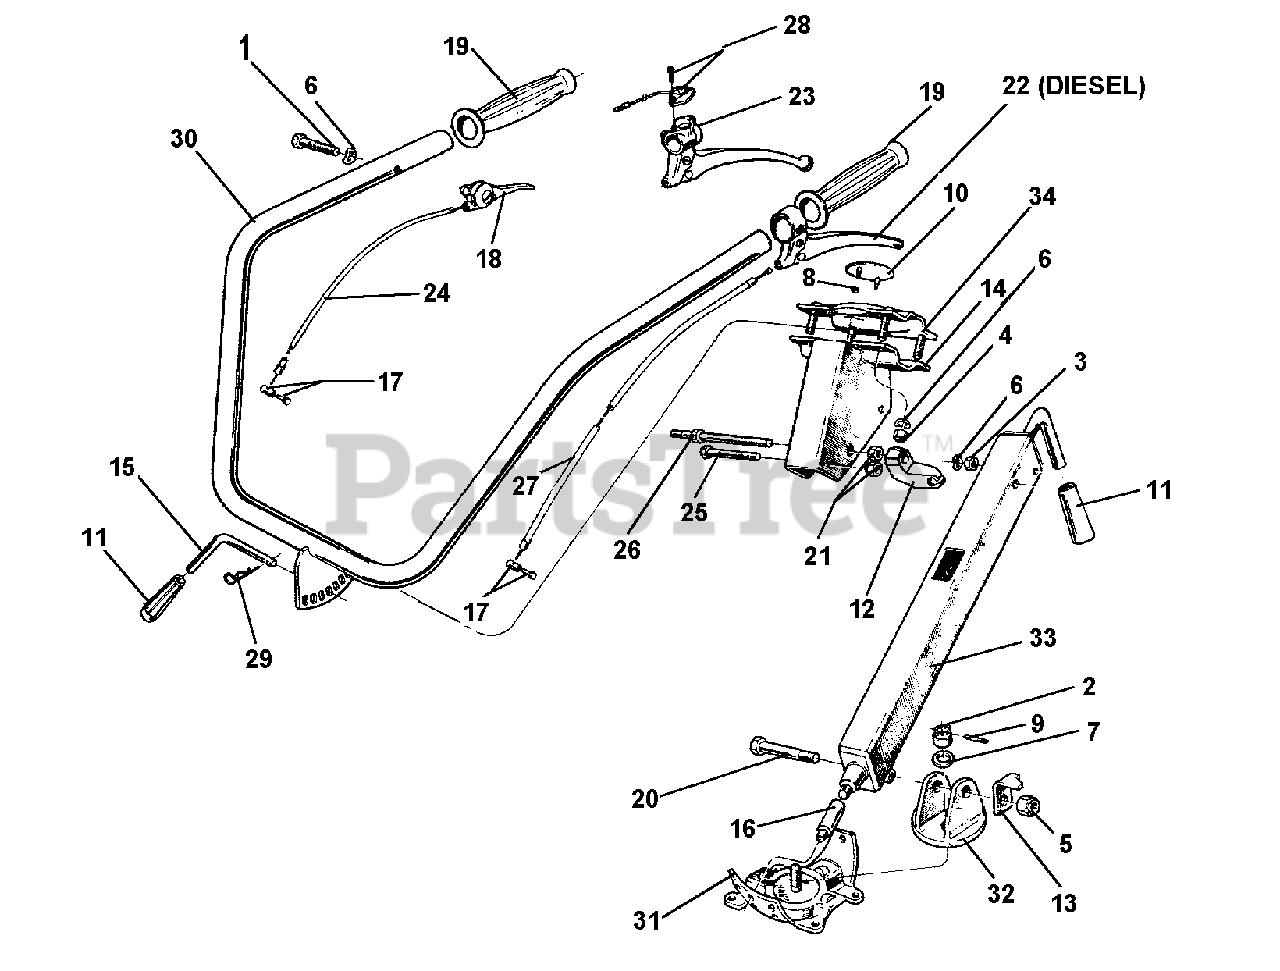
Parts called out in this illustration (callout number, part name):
1	SCREW TE M8 X 40
2	NUT, HEX INT. M12 UNI 5593 6S
4	NUT, SELF LOCKING M8
5	NUT, SELF LOCKING M12
6	WASHER,LOCK 8.4
7	WASHER, LOCK 13
8	WASHER, LOCK FOR PINS D-4
9	PIN, LOCKING SW 3 X 22 SPIRAL
12	SUPPORT CONTROL ROD CUT
13	LOCKING PLATE
15	LEVER FOR SECTOR
17	CLAMP, CABLE
18	LEVER ACCELERATOR
19	KNOB RUBBER HOLE D 25
20	SCREW SPECIAL M12 X 70
21	BEVEL NUT M8
22	CLUTCH LEVER (DIESEL)
23	CLUTCH LEVER
24	WIRE, SHEATH 1850 GAS
25	SCREW STEERING COLUMN M8 X 58
26	SCREW STEERING COLUMN M8 X 118
27	WIRE SHEATH L-1280 CLUTCH/BR.
31	CAP WITH HOLE D.13
33	STEERING COLUMN
